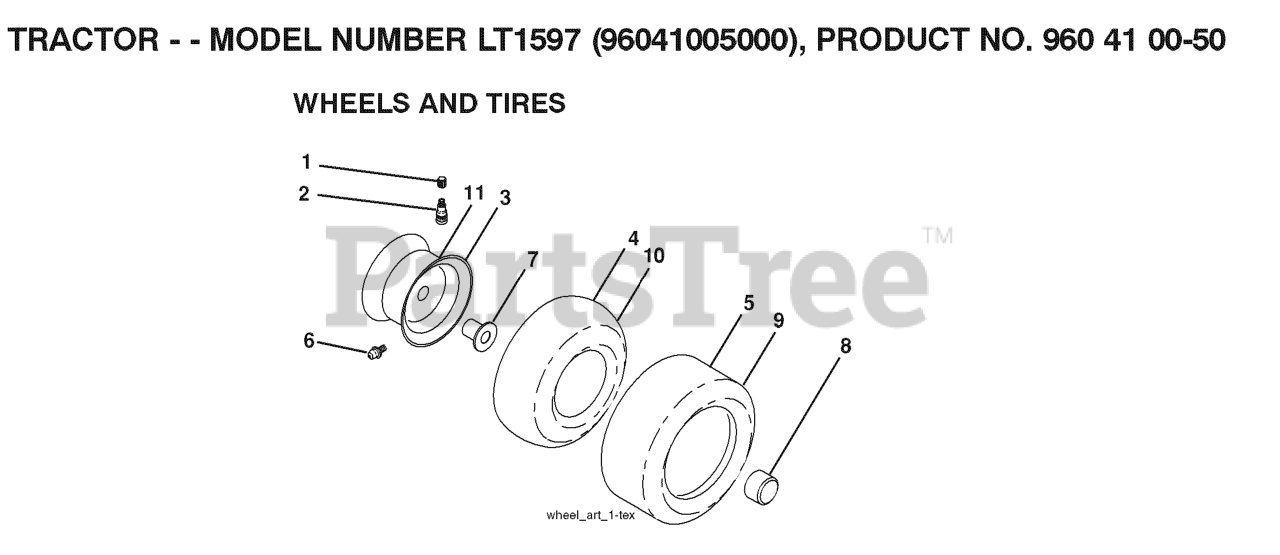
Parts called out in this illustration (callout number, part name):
2	VALVE STEM LT
3	RIM ASM 6" FRONT SILVER
4	TUBE.5.3/4.5/6
5	TIRE HEAVY DUTY
6	FITTING LT
7	BEARING T
8	CAP, AXLE BLK
9	TIRE HEAVY DUTY
10	TUBE
11	RIM ASM 8" REAR SILVER
